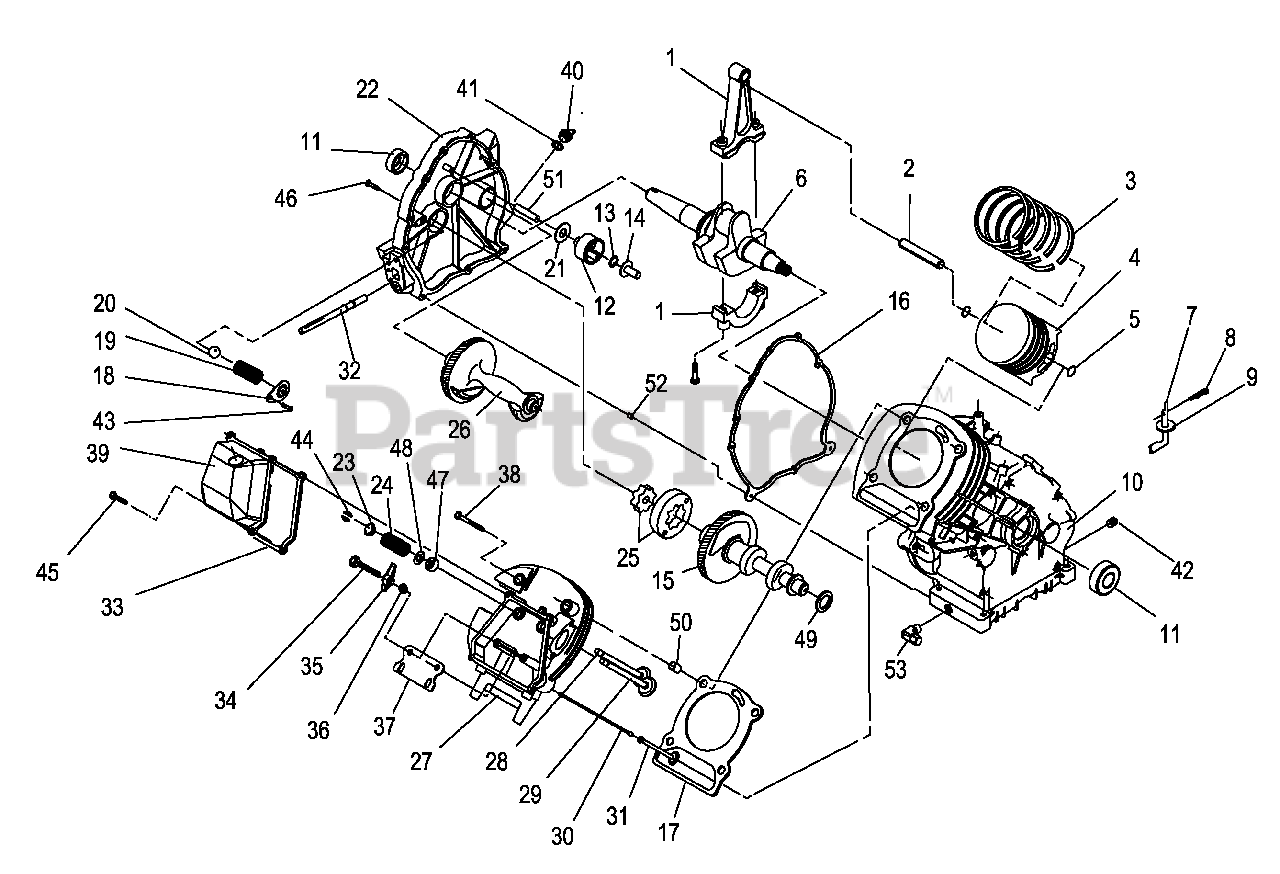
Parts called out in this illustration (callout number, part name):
1	ASSEMBLY, CONNECTING ROD
2	PIN, PISTON D20
3	RING SET, PISTON DIA90
4	PISTON, FLAT TOP DIA90 COATED
5	RETAINER, PISTON PIN 20
6	ASSEMBLY, CRANKSHAFT GH410 SMALL TAPER
7	ARM, GOVERNOR RC45
8	PIN, "R" GOVERNOR ARM
9	WASHER, GOVERNOR ARM THRUST
10	CRANKCASE, SUBASSEMBLY WITH PLUGS GH410
11	SEAL, 35 I.D. CRANKSHAFT
12	ASSEMBLY, GOVERNOR GEAR
13	C-RING, GOVERNOR GEAR RETAINER
14	SPOOL, GOVERNOR- MACHINE
15	ASSEMBLY, CAMSHAFT & GEAR
16	GASKET , CRANKCASE
17	GASKET, HEAD 410
18	COVER, OIL PRESSURE RELIEF
19	SPRING, OIL RELIEF 360
20	BALL, DIA 11/32 PRESSURE RELIEF
21	WASHER, THRUST GOVERNOR GEAR
22	ASSEMBLY, COVER, GEAR TOP CHECK / FILL
23	RETAINER, VALVE SPRING
24	VALVE SPRING LF
25	SET,GEROTOR 12 THK
26	BALANCER
27	ASSEMBLY,CYLINDER HEAD SEATS & GUIDES
28	VALVE, EXHAUST
29	VALVE, INTAKE
30	PUSH ROD 174.9
31	TAPPET
32	ASSEMBLY, SCREEN OIL PICK-UP
33	GASKET, ROCKER COVER 410
34	STUD, D20 PIVOT BALL
35	ROCKER ARM
36	NUT, JAM (ROCKER ARM)
37	PLATE, PUSH ROD GUIDE
38	SCREW, HHFL M10-1.5 X 105
39	ASSEMBLY, ROCKER COVER GENERAC TEXT
40	PLUG, OIL FILL PLASTIC
41	O-RING 17.8 I.D. x 2.4
42	PLUG, STANDARD PIPE 3/8 STEEL SQUARE HEAD
43	SCREW, TAPTITE M5-0.8 X 10 BP
44	KEEPER, VALVE SPRING
45	SCREW & LOCKWASHER M6-1 X 12
46	SCREW, HHFC M8-1.25 X 42
47	SEAL, VALVE STEM D7
48	WASHER, VALVE SPRING
49	WASHER, LARGE SPRING
50	SLEEVE, DOWEL PIN 14 DIA.
51	SHAFT, GOVERNOR RC55
52	SLEEVE, DOWEL PIN 12 DIA.
53	OIL DRAIN FITTING
